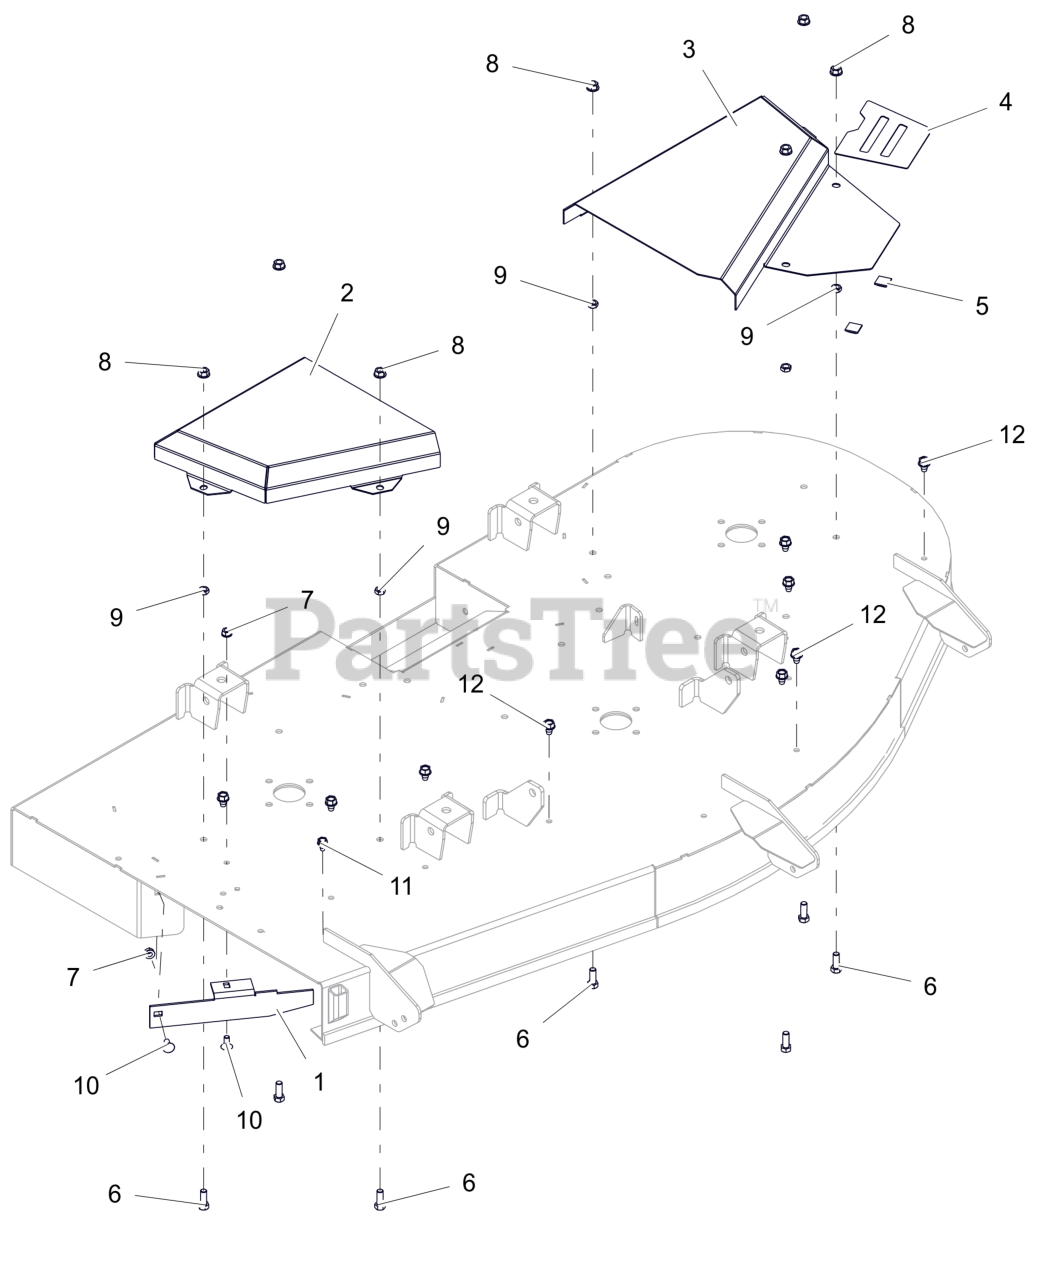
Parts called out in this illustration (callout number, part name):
1	BAFFLE, DISCHARGE 60
2	COVER, RH BELT 60
3	COVER, LH BELT 60
4	GRIP TAPE 52-60 BELT COVER
6	BLT,HEX .38-16X1.00 G5 ZCC
7	NUT-LK-TOP-FLG .312-18 GF ZCC
8	NUT-LK-CTR-FLG .375-16 GF ZCC
9	NUT-JAM .375-16 G2 ZCC
10	BLT,RHSN .31-18X.75 G5 ZCC
11	SCR,TAP .312-18X.50 HWH TR ZCC
12	SCR,TAP .375-16X.50 HWH TR ZCC
